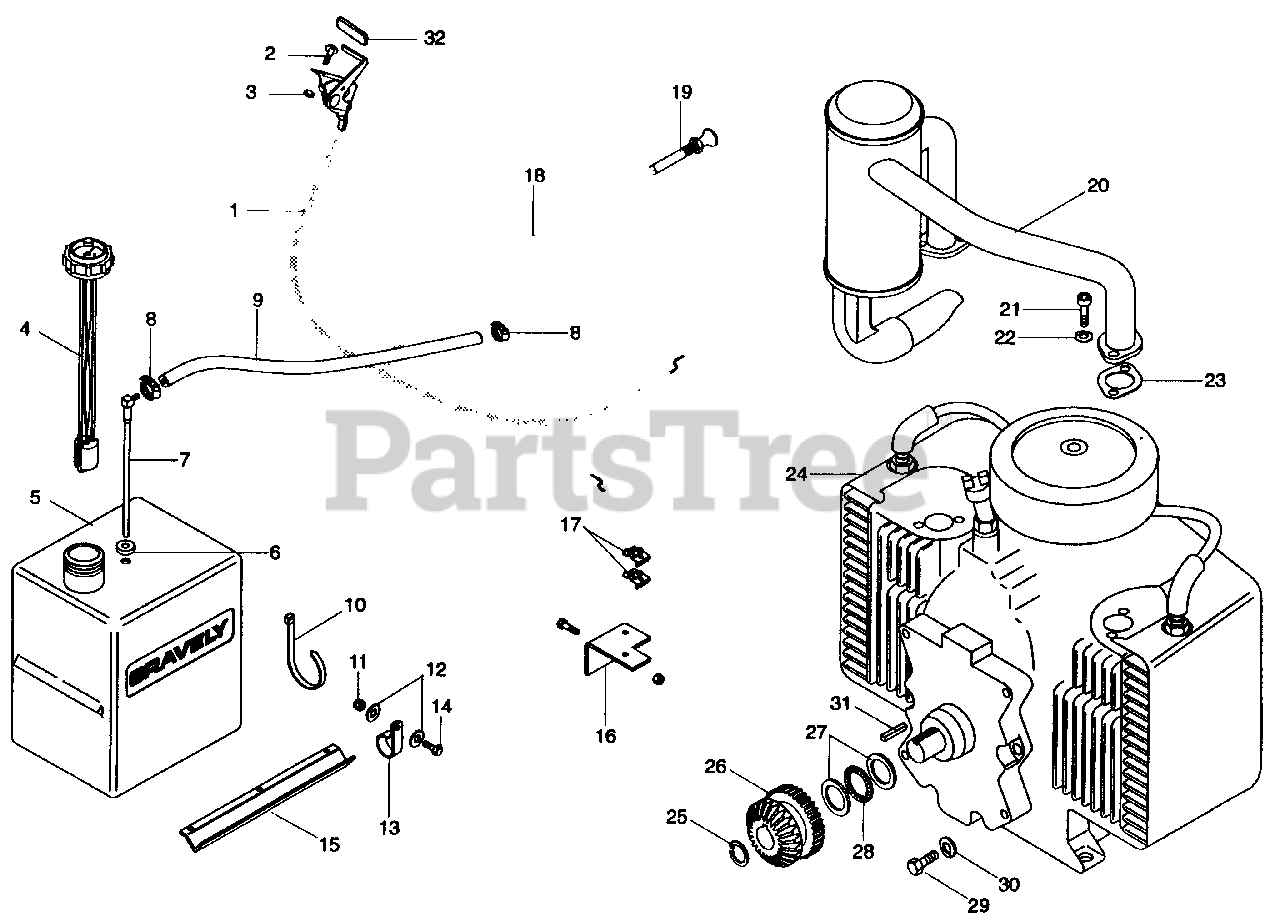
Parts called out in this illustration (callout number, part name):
1	THROTTLE CABLE
2	SCR-MACH 10-32 X .50 PH D
3	NUT-LK 10-32 NY PL
4	GA, FUEL
5	TANK FUEL
6	BUSHING
7	FTG. TANK
8	CLAMP-HOSE
9	GASOLINE, BULK
10	TIE, CABLE
11	NUT-LK-NYL .312-18 PL
12	WSHR-FL-STL .344 X .688 X .065
13	CABLE CLAMP
14	BLT-HEX .31-18 X 1.000 PL GR 5
15	SHIELD, HEAT
16	BRKT, THROTTLE & CHOKE
17	CLIP, SPEED
18	CONTROL, CHOKE
19	NUT-JAM .375-24 PL
20	MUFFLER, EXHAUST
21	SCR-CAP .31-18 X .75 S/HD
22	WSHR-LOCK .313 X .078 PL
23	GASKET, EXHAUST
24	ENG, 16 HP MAGNUM, PS-24633
24	ENG, 18 HP MAGNUM, PS-24590
24	ENG, 20 HP S.B. KOHLER PT .49562
25	RG-RTNG-INT 1.249 X .050
26	INPUT GEAR
27	WSHR-THRST 1.125 X 1.750 X .123
28	BRG-N-THRST 1.74 X 1.127 X .078
29	BLT-HEX .50-13 X 1.75
30	WSHR-LOCK .50 REG
31	KEY, SQ .248 X 1.25 X .248
32	GRIP
